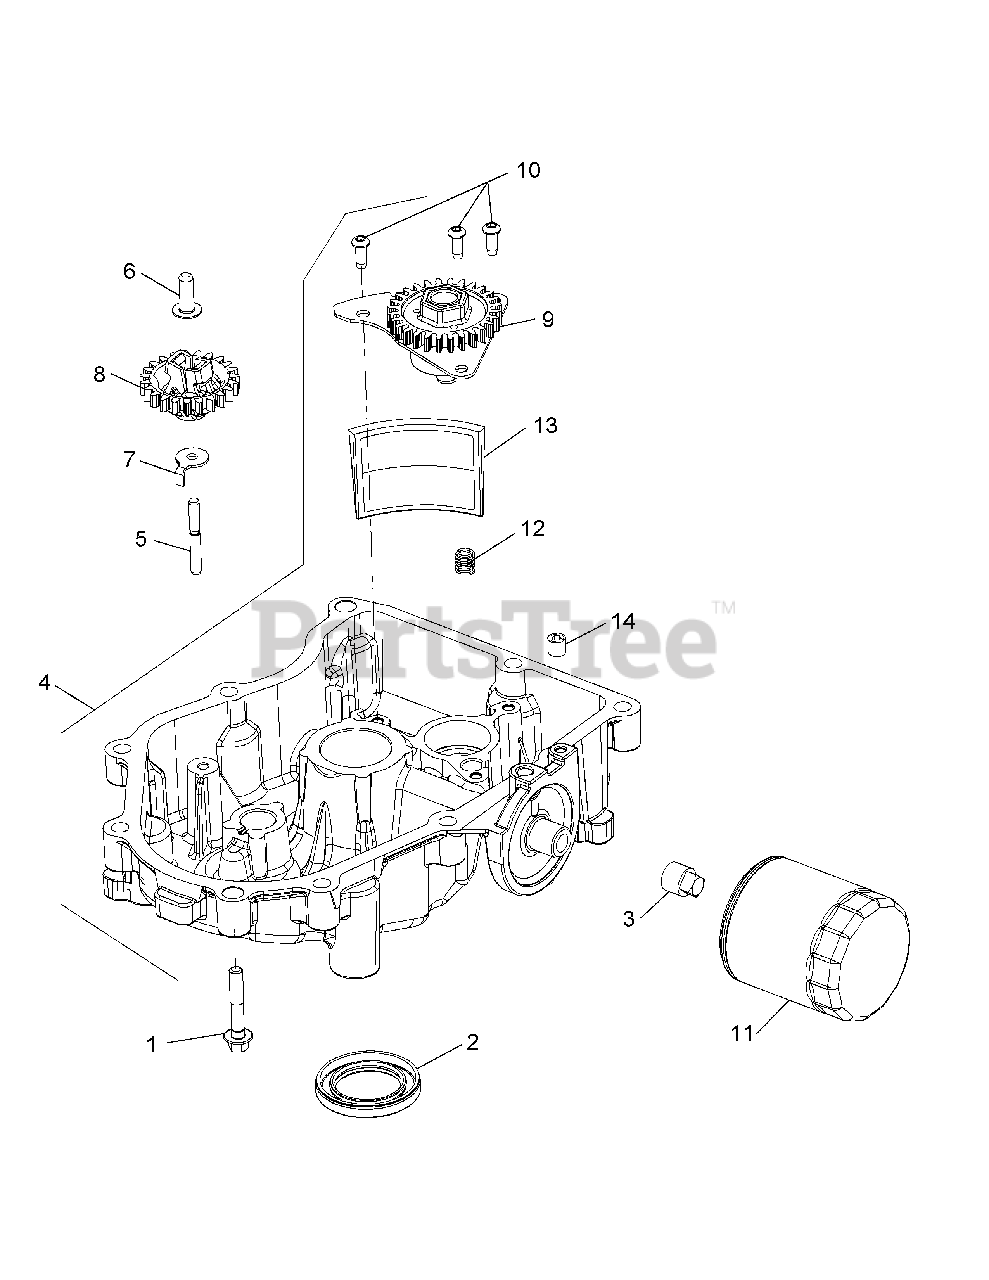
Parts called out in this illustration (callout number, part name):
1	Flange Screw, M8 x 1.25 x .45
3	Pipe Plug, 3/8
4	Oil Pan Assembly
5	Governor Gear Shaft
6	Governor Regulating Pin
8	Governor Gear Kit
9	Oil Pump Assembly
10	Button Head Screw
12	Compression Spring
14	Pipe Plug, 1/8
